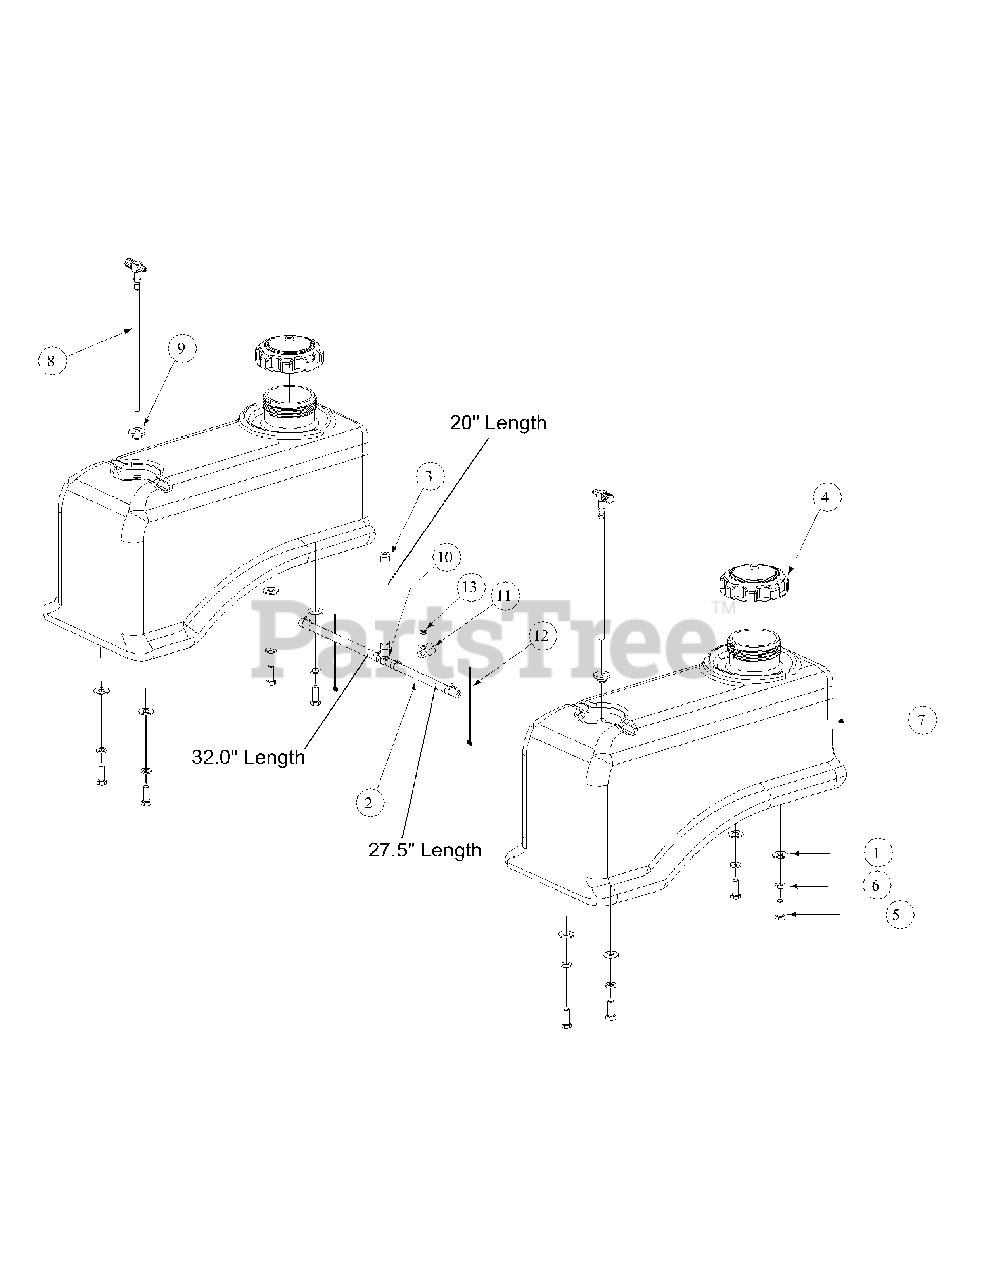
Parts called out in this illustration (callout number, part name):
1	Flat Washer, .406 ID, 1.0 OD, .105
2	Hose, 1/4" Fuel Line 79.5"
3	Clamp, Union
4	Fuel Cap, 3.5
5	Hex, Cap Screw, 3/8-16, .88
6	Lock Washer, 3/8
7	Fuel Tank
8	Fuel Fitting
9	Fuel Tank Grommet
10	Tee Fitting, Fuel
12	Cable Tie
13	Flatwasher 1/4 x .630 x .0515
